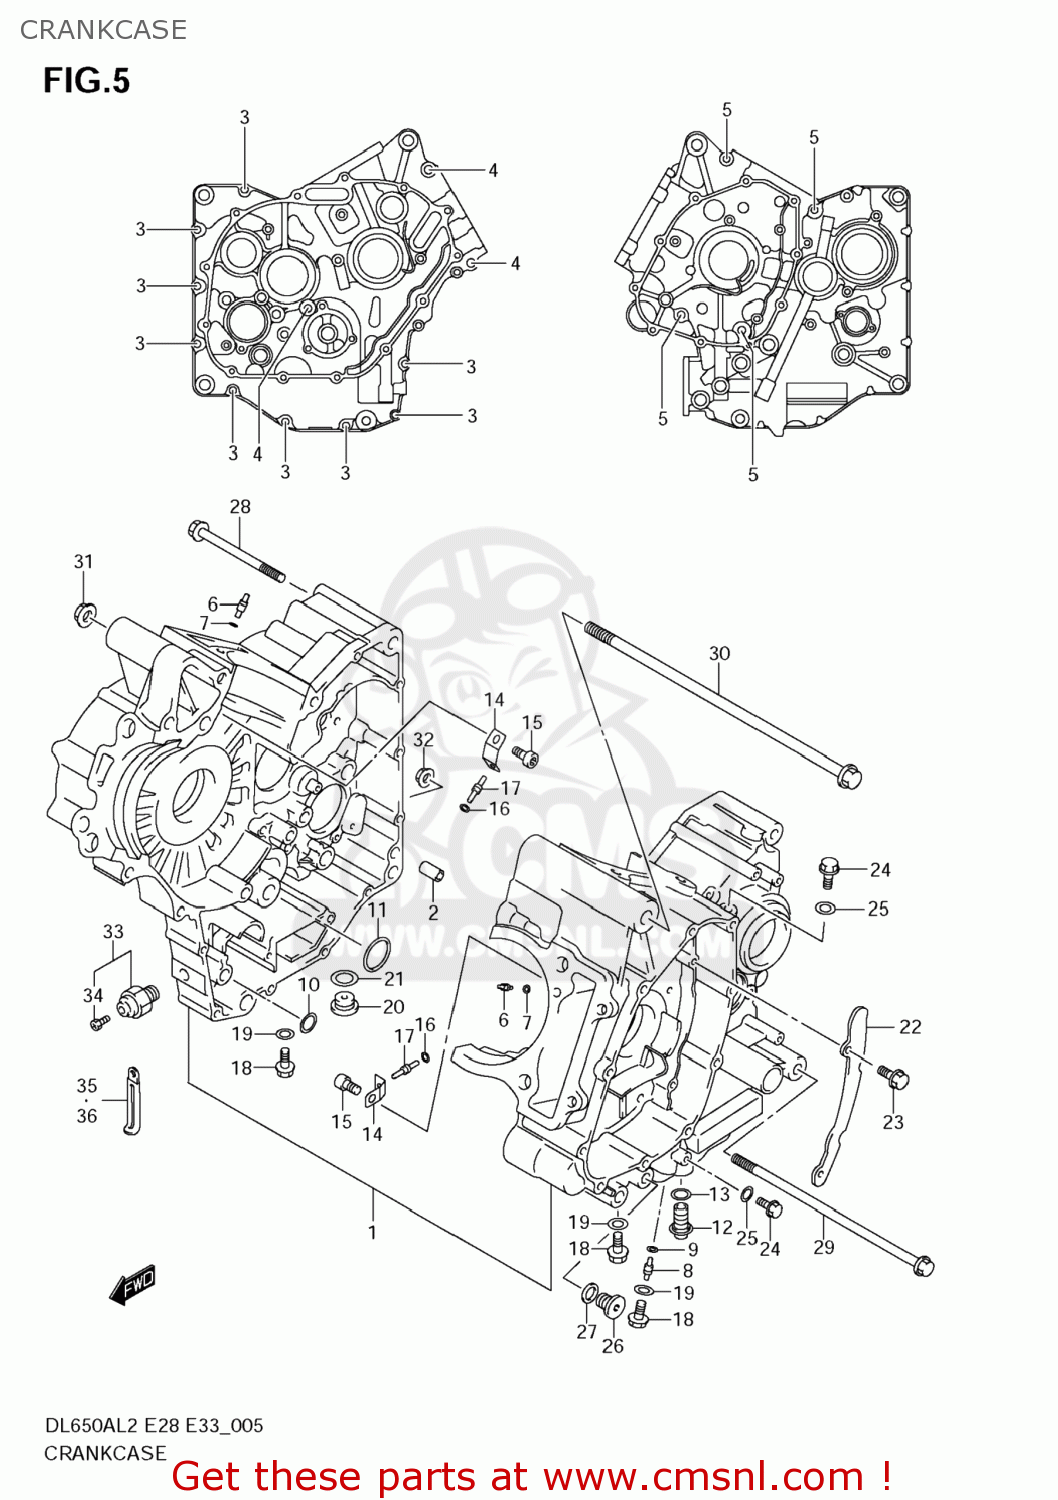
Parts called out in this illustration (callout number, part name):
1	CRANKCASE SET
2	PIN(8.4X11X20)
3	BOLT
4	BOLT
5	BOLT
6	JET,AIR(14)
7	O RING(D:1.2,ID:4)
8	JET,OIL GALLERY(18)
9	O RING(D:1.2,ID:4)
10	O RING(D:1.9,ID:12.6)
11	O RING(D:2.4,ID:15.8)
12	PLUG(12X20)
13	GASKET(12.1X16.2X3.7) (NAS)
14	PLATE,PISTON COOLING JET
15	BOLT(6X12)
16	O RING(D:1.2,ID:4)
17	JET(13)
18	BOLT
19	GASKET(8.2X14X1) (NAS)
20	PLUG,16X8
21	GASKET(16X22X2) (NAS)
22	PLATE,OIL SEPARATOR
23	BOLT
24	BOLT
25	GASKET(5.8X13X1.2) (NAS)
26	PLUG(12X10)
27	GASKET(12X17X1) (NAS)
28	BOLT(10X225)
29	BOLT(10X275)
30	BOLT(12X310)
31	NUT
32	NUT
33	SWITCH ASSY,OIL PRESSURE
34	BOLT,OIL PRESSURE SWITCH
35	CLAMP(L:45)
36	CLAMP(L:80)
